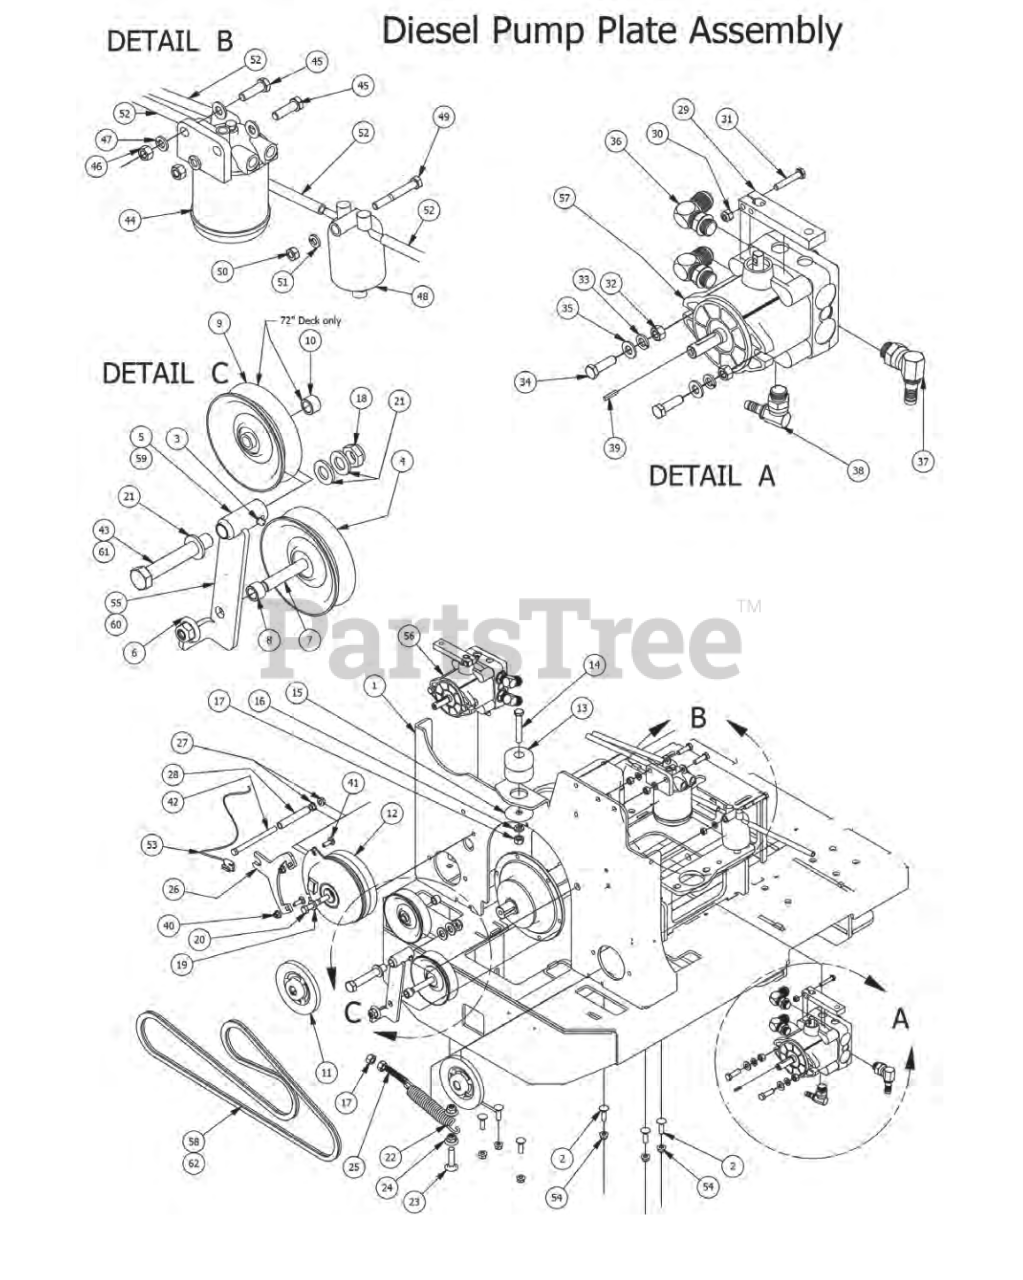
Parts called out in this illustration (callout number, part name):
1	Pump Plate Diesel
2	3/8" x 1 1/4" Carriage Bolt
3	1/4" Drive in Grease Fitting
4	4 3/4" Idler Pulley
5	Pump Idler Bracket only for 61" Deck
6	1/2-13 Nylon Flange Nut-Orange
7	1/2" x 3" Hex Bolt
8	1/2 x 1/2 Spacer
9	5 Idler Pulley only for 72" Deck Diesel
10	5/8" x 1/" Collar Spacer only for 72" Deck Diesel
11	S" Pump Pulley
12	Clutch Assembly for Diesel
13	Armor Plated Mount-Rear Mount
14	1/2" x 3" Hex Bolt
15	Snubbing Washer
16	1/2" Lock Washer
17	1/2" Hex Nut
18	5/8" Nylock (1/2 Jam)
19	7/16" Lock Washer
20	7/16" x 2 3/4" Fine Thread Bolt
21	630 ID x 1.122 OD X,142 THK Plastic Washer
22	Deck Idler Spring
23	1/2 x 2" Carriage Boit
24	1/2-13 Nylon Flange Nut-Orange
25	1/2-13 x 2-1/2 All Thd Stud
26	Diesel PTO Engager Holder
27	3/8 Flange Nut
28	3/8 hose 4" long
30	1/4" Nylock Nut
31	1/4" x 1 1/2" Bolt
32	3/8" Hex Nut
33	3/8" Lock Washer
34	3/8" x 1 1/2" Hex Bolt
35	3/8" Flat Washer
36	90 Degree Adaptor 6801-L-8-8 Fitting
37	90 Degree Fitting 1/2" x 3/4" 4601-8-8
38	90 Degree Fitting 3/8" x 9/16"-4601-6-6
39	5mm x 1.25" Key
40	5/16" Flange Nut
41	5/16" x 1" Carriage Bolt
42	3/8-16 x 5 Hex Bolt - Grade 5
43	5/8" x 4" Hex Bolt 61" Deck only
44	Fuel Filter
45	3/8" x 1 1/4" Hex Bolt
46	3/8" Hex Nut
47	3/8" Lock Washer
48	Caterpillar Fuel Bowl Kit
49	5/16" x 2 1/2" Bolt
51	5/16" Lock Washer
52	5/16" fuel line hose
53	Clutch Pigtail
54	3/8" Nylock Flange Nut
55	Pump Idler Assembly Components 3,4,5,6,7,8, only for 61" Deck
56	Left Pump 16cc-AOS Diesel 35Hp Diesel
57	Right Pump 16cc-AOS Diesel 35Hp Diesel
58	Pump Belt for 72" Deck
59	Diesel Pump Idler only on 72" Deck
60	Diesel Pump Idler Assembly Components 3,4,5,6,7,8,9,10 only for 72" Deck
61	5/8 x 5 1/2 Bolt only for 72" Deck
62	Pump Belt for 61" Deck
